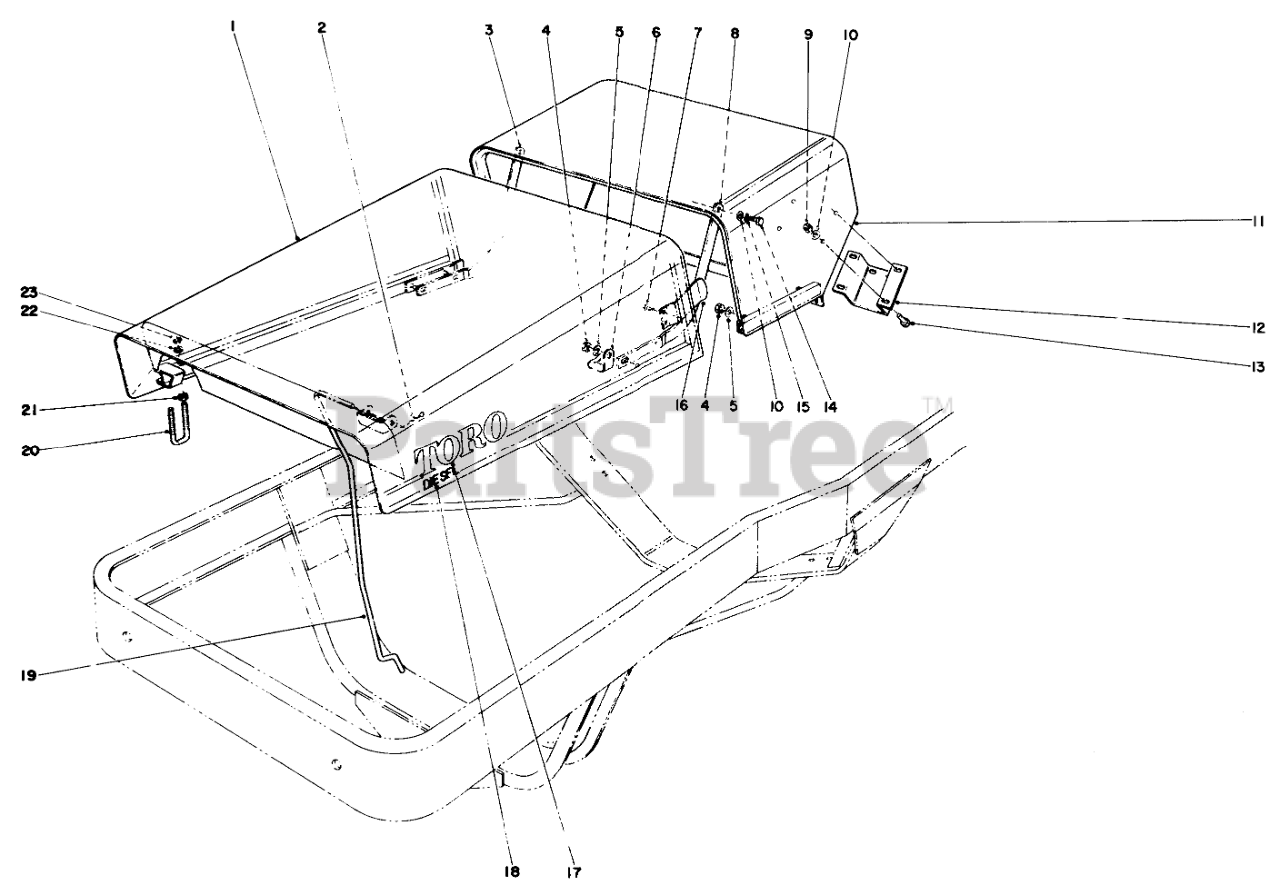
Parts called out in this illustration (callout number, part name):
1	BEZEL-HEADLIGHT, LH
2	BEZEL-HEADLIGHT, RH
3	HEADLAMP
4	HARNESS-HEADLIGHT
5	LOCK-HEADLIGHT
6	SCREW-HWH
7	EDGING-CONSOLE
9	RIVET-POP
10	HANDLE ASM
11	NUT-LOCK, NI
12	WASHER-FLAT
13	BRACKET-GRILL, LH
14	SCREW-CARR
15	ROD-HOOD STOP
16	PIN-COTTER
17	BUSHING-NYLINER
18	RING-RETAINING
19	ROD-GRILL PIVOT
20	BRACKET-GRILL, R H
22	TIE-CABLE
23	LOGO - HORSEHEAD
24	DECAL-FRONT HOOD, TOP
25	DECAL - RH HOOD TOP
26	DECAL-DANGER, HOOD
27	DECAL - LH HOOD TOP
28	Hood
